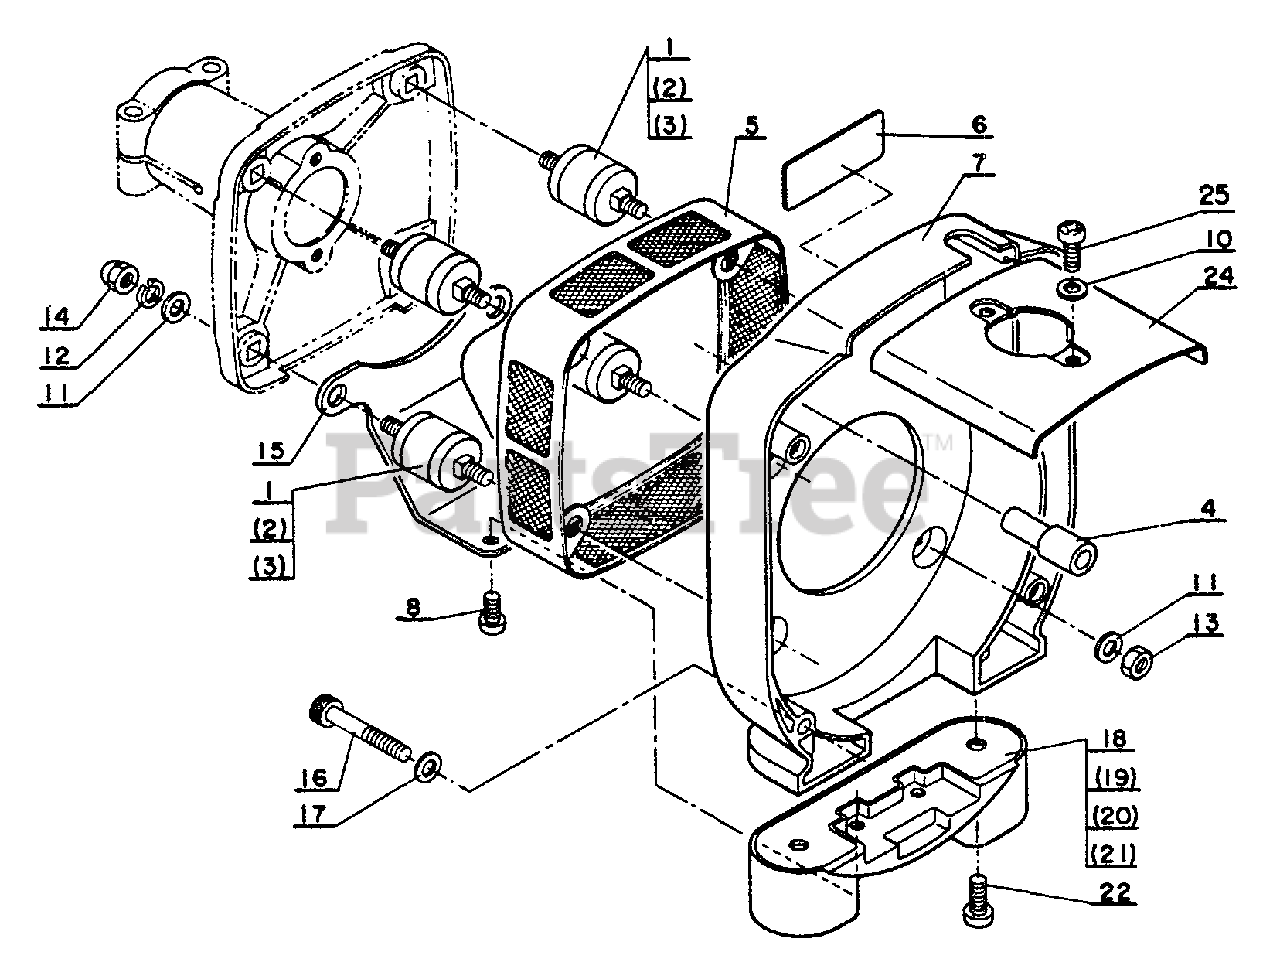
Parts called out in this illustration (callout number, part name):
1	CUSHION - UPPER
4	TUBE
5	SEAL, DUST
6	MODEL PLATE
7	CASE, FAN
8	SCREW 4×12
10	WASHER 4 MM
11	WASHER, FLAT 5.5×10×0.8
12	WASHER, SPRING 5
13	LOCKNUT - 5
14	NUT - 5
15	CUSHION SUPPORTER
16	SCREW - 5×35
17	WASHER
18	CUSHION - LOWER
22	SCREW 5×12
24	COVER, ENGINE
25	SCREW 4×8
